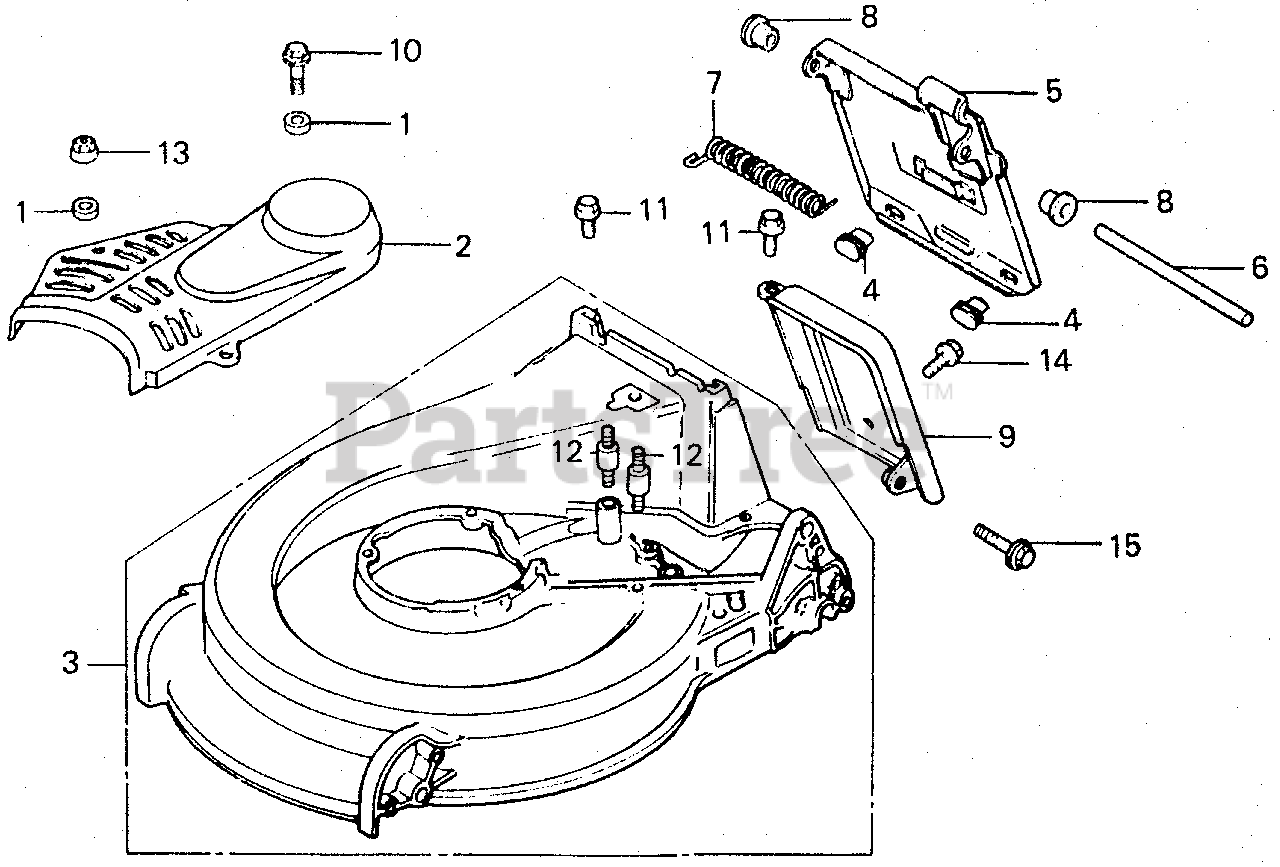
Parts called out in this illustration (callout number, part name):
1	COLLAR, FAN
2	COVER, BELT (NOT AVAILABLE)
3	HOUSING, CUTTER *NH2M* (METALLIC SILVER)
4	STOPPER, DISCHARGE GUARD
5	GUARD, DISCHARGE
6	SHAFT, DISCHARGE GUARD (NOT AVAILABLE)
7	SPRING, GUARD RETURN (NOT AVAILABLE)
8	BUSH, DISCHARGE GUARD
9	PANEL, BAG OPEN *NH2M* (METALLIC SILVER)
10	BOLT, FLANGE (6X14) (CT200)
11	BOLT, FLANGE (6X20) (CT200)
12	BOLT, STUD (6X28) (CT200)
13	NUT, FLANGE (6MM)
14	BOLT, FLANGE (6X12)
15	BOLT, FLANGE (6X25)
